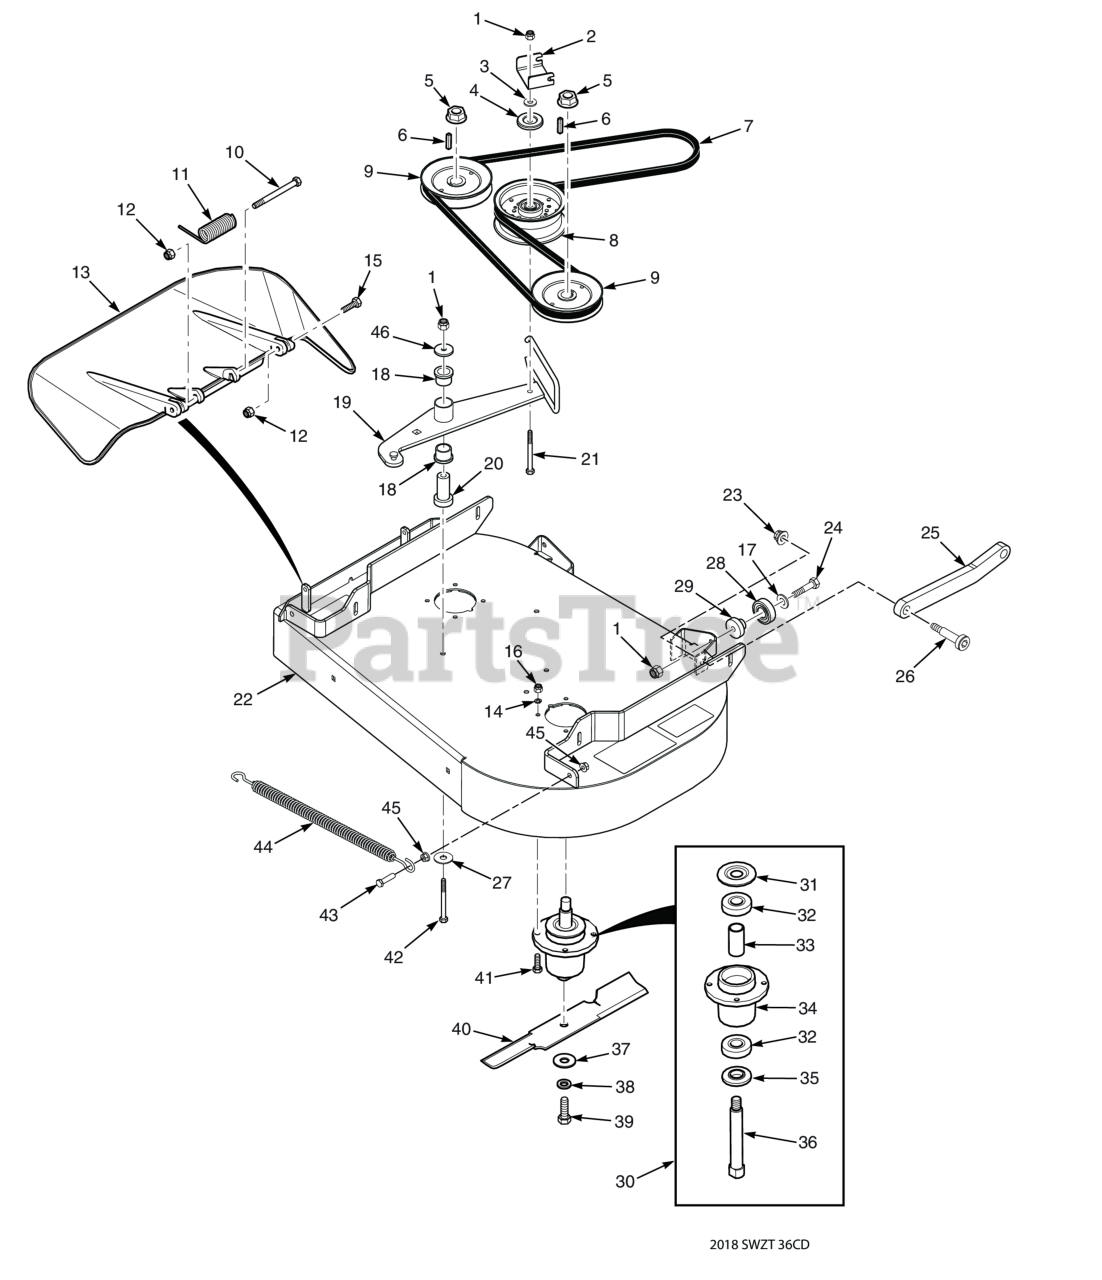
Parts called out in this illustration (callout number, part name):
1	HEX NUT, ELASTIC STOP LOCK, 3/8-16
2	Bracket, Belt Guide
3	Flatwasher, 3/8 (.391 x .938 x .105 HD) Grade 8
4	Quick Pin, 5/16" Dia.
5	Nut, 3/4-16 Spriral Lock
6	Key, 1/4 x 1/4 x 1.25" Pulley Mtg.
7	Belt, Cutter Deck
8	Pulley, Idler 5" Dia.
9	Pulley, 5.73" OD - 25mm Bore
10	Bolt, 5/16-18 x 4-3/4" Hex Head
11	Spring, Discharge Chute
12	HEX NUT, ELASTIC STOP LOCK, 5/16-18
13	Discharge Chute Assy. SFZ48
14	Lockwasher, 5/16 (.317 x .586 x .078) Helical Spring
15	Bolt, Hex Head 5/16-18 x 1-1/2" - Front
16	Lock Nut, 5/16-18 Elastic Stop Grade 8
17	Flatwasher, 3/8 (.391 x .938 x .105 HD) Grade 8
18	Bearing, Plastic
19	Idler Arm Assembly
20	Pivot, Idler
21	Capscrew, Hex Head 3/8-16 x 3.25"
22	Cutter Deck w/Decals, SMWZT-36
23	Nut, Flange Elastic Stop Nut, 3/8-16
24	Bolt, Hex Head 3/8-16 x 1-3/4" (Kohler EFI)
25	Pusharm
26	Bolt, Shoulder 1/2 x 3/8-16 x 2-3/4"
27	Flatwasher, 3/8-.406 x 2.25" x .1875
28	Bearing
29	Spacer, Bearing
30	Spindle Assembly
31	Debris Shield
32	Bearing
33	Spacer, Bearing
34	Spindle Housing Assembly
35	Protector, Bearing
36	Shaft, Spindle
37	Flatwasher, 5/8-.688 x 1-3/4 x .134 HD
38	Lockwasher, 5/8" Spring
39	Bolt, Hex Head 5/8-11 x 1-1/2"
40	Cutter Blade, 18" (52V)
41	Bolt, Hex Head 5/16-18 x 1-1/2" Grade 8
42	Capscrew, Hex Head 3/8-16 x 3-3/4"
43	Bolt, Hex Head 3/8-16 x 1-1/2" Grade 8 Black
44	Spring, Cutter Deck Idler
45	NUT, 3/8-16 SERRATED FLANGE HEX HEAD
46	Flatwasher, 3/8-.406 x 1-1-1/2 x 7 Gauge
